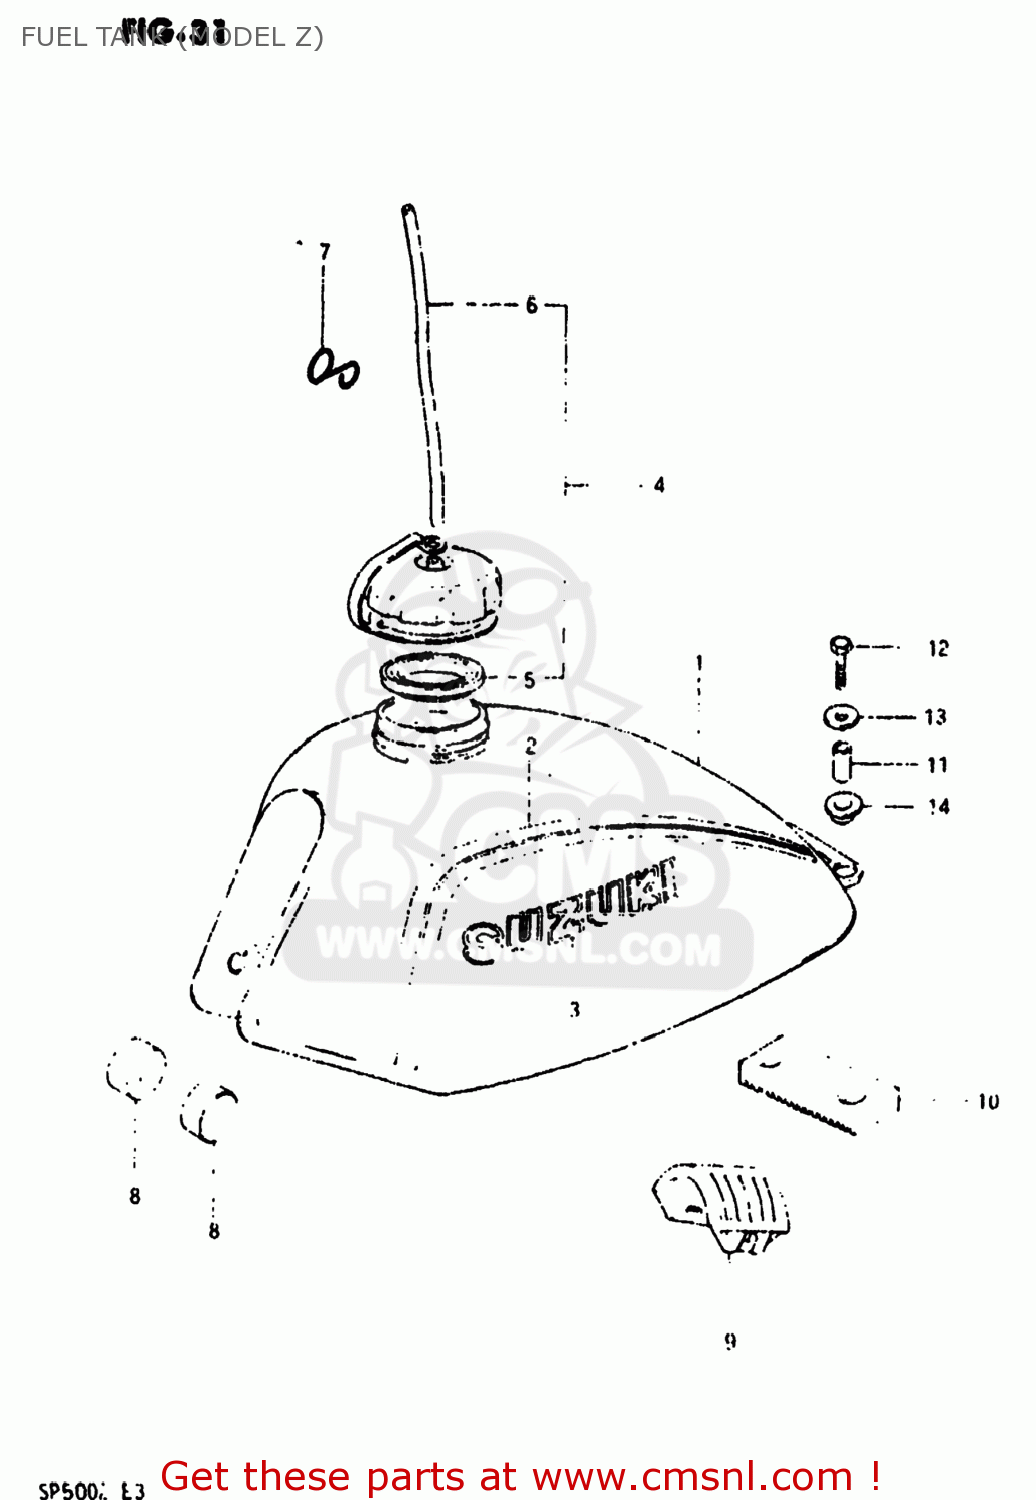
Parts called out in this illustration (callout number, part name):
1	TANK ASSEMBLY,FUEL
2	TAPE SET,FUEL TANK
3	EMBLEM,FUEL TANK(WHITE)
4	CAP,FUEL TANK
5	GASKET,FUEL TANK CAP (NAS)
6	HOSE,FUEL
7	GUIDE,CABLE
8	CUSHION
9	CUSHION,FUEL TANK UPR FR
10	CUSHION,FUEL TANK,REAR
11	SPACER (6.5X10.5X29)
12	BOLT 6X40
13	WASHER (6.5X24X1.6)
14	CUSHION
